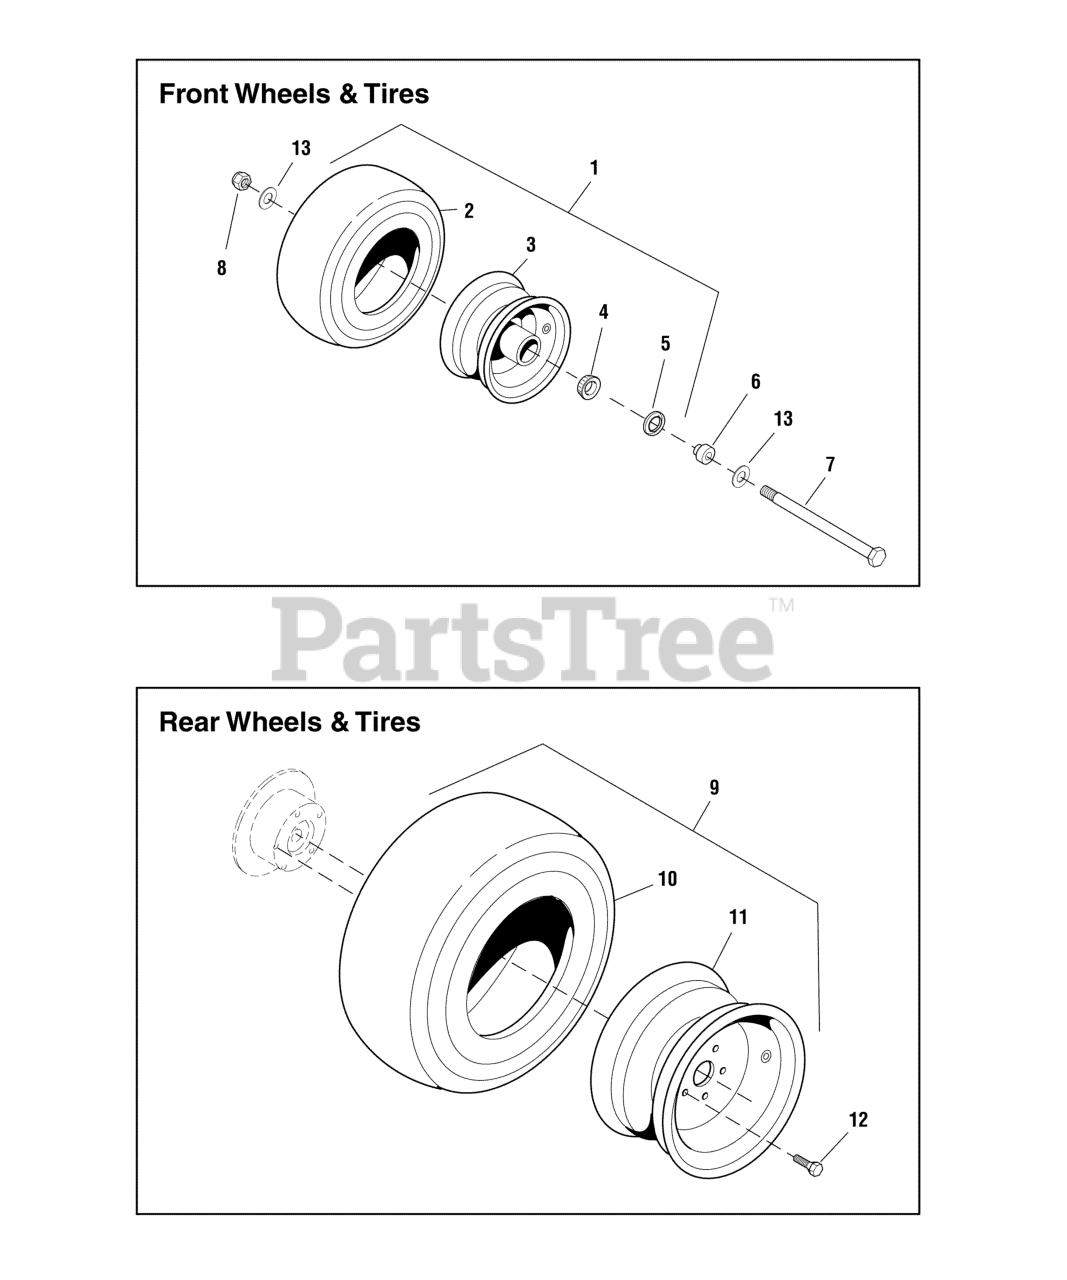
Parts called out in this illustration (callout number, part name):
1	TIRE ASSM, 13 X 6.5 - 6, PNE / TB
2	TIRE, RUBBER ONLY
3	WHEEL ASSEMBLY, for 13 x 6.5 x 6 Tires, Complete
4	BEARING, Tapered Roller
5	SEAL, GREASE
6	ADAPTER, CASTER AXLE, CZ
7	BOLT, 1-2/13 x 9
8	NUT, 1/2-13 HEX NYLON LOCK
9	TIRE WHEEL ASM, 24X12.00-12, TURF MASTER
10	TIRE, 24 X 12 X 12
11	WHEEL, 12 X 8.5
12	WHEEL LUG, 1/2 x 1-5/8
